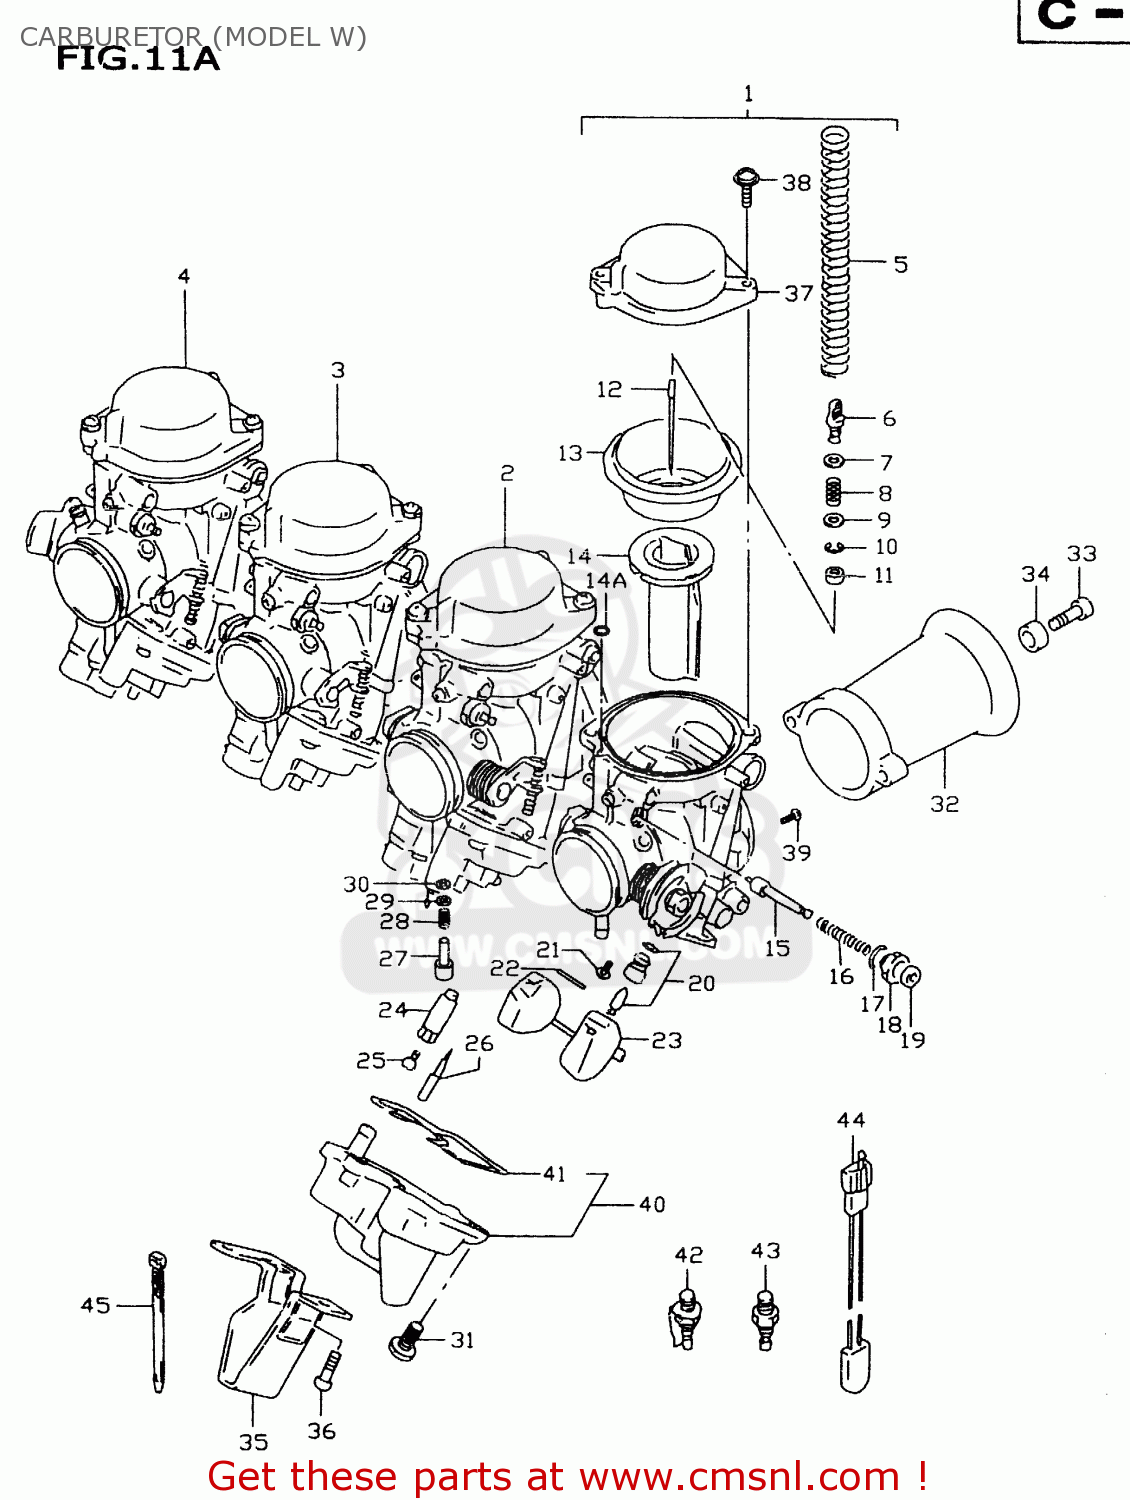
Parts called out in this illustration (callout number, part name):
1	CARBURETOR ASSY,L
2	CARBURETOR ASSY, ML
3	CARBURETOR ASSY,MR
4	CARBURETOR ASSY,R
5	SPRING
6	HOLDER
7	O RING(D:1.9,ID:4.8)
8	SPRING
9	WASHER
10	E RING,MULTIPLE JET NOZZLE
11	RING
12	NEEDLE,JET
13	DIAPHRAGM
14	VALVE,PISTON
14A	O RING
15	PLUNGER
16	SPRING
17	O RING
18	GUIDE SCREW,PLUNGER
19	CAP,STARTER VALVE
20	VALVE ASSY,NEEDLE(NI)
21	SCREW
22	PIN,FLOAT
23	FLOAT ASSY
24	HOLDER,JET
25	JET,MAIN(135)
26	JET,PILOT(12.5)
27	ADJUSTER
28	SPRING,THROTTLE SCREW
29	WASHER
30	O RING,PILOT AIR SCREW
31	SCREW
32	FUNNEL
33	SCREW
34	RING
35	BRACKET
36	SCREW
37	COVER ASSY,DIAPHRAGM
38	SCREW
39	JET,MAIN(135)
40	BODY ASSY,FLOAT,L
41	O RING
42	HEATER ASSY,CARBURETOR(15W)
43	HEATER, CARB.
44	THERMO SWITCH,CARB HEATER
45	CLAMP(L:125)
